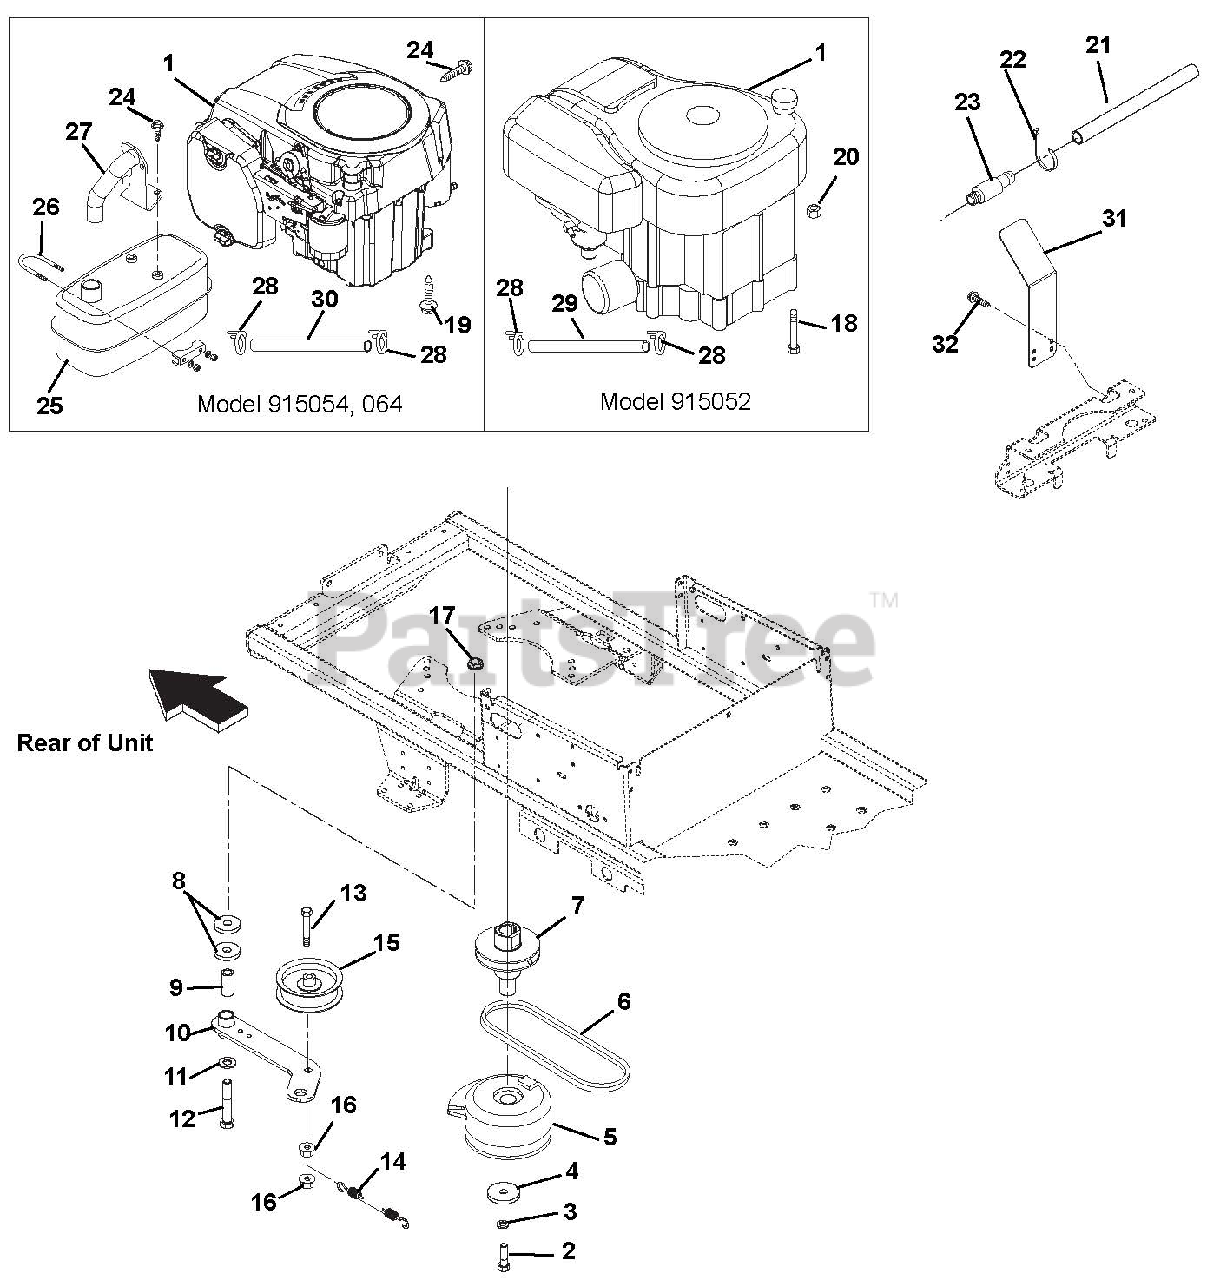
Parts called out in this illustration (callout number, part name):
1	Engine, 15 hp Kohler
1	Engine, 14hp Briggs & Stratton
2	Bolt, Hex .44-20 x 4.50 Grade 8
3	Washer, Locking .44 x .109 Regular
4	Washer, Flat Steel .469 x 2.00 x .25
5	Electric Clutch, Brake 3.4 Amp
7	Crankshaft Extension
8	Washer, Flat Steel .515 x 1.625 x .250
9	Bushing, Sleave .500 x .750 x .1.560
10	Weldment, Idler
11	Washer, Flat Steel .531 x 1.06 x .095
12	Bolt, Hex .50-13 x 3.25
13	Bolt, Hex .38-16 x 2.25 Grade 5
14	Spring, Extension
15	Idler, Flanged 3.50
16	Nut, 3/8-16 Flange Nyloc
17	Nut, Locking Top Flange .50-13
18	Bolt, Hex .31-18 x 1.75 Grade 5
19	Screw, Tapping .38-16 x 1.00 Hex Washer Head
20	Nut 5/16-18 Flange Nyloc
21	Tube, Oil Drain
22	Cable Tie
23	Valve, Oil Drain
24	Screw, Tapping .25-20 x .50 Hex Washer Head
25	Muffler, Kohler Courage Single
26	Clamp, Muffler
27	Weldment, Manifold
28	Clamp, Hose Wire .490/.510 x .092
29	Gas Line, Bulk 16" LG
30	Gas Line, Bulk 18" LG
31	Heat Shield, Mini Z
32	Screw, Tapping .31-18 x .50
